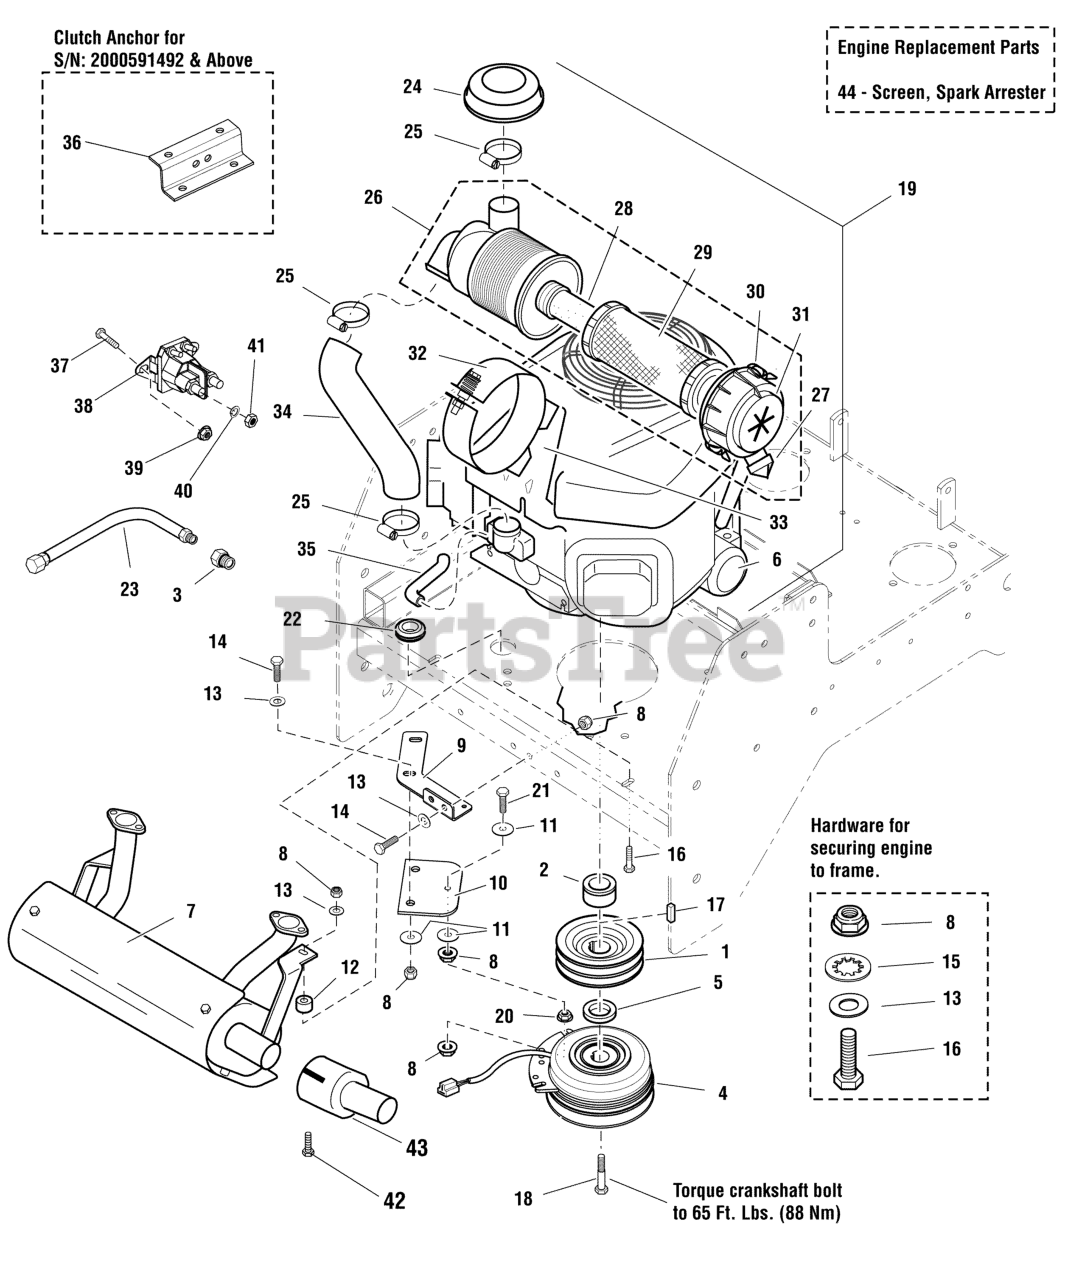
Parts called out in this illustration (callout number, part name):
1	PULLEY CRANKSHAFT (DOUBLE A)
2	SPACER, 1.13 X 1.75 X 1.03
3	ADAPTER, OIL DRAIN
4	* CLUTCH, 5218-134, WARNER
5	SPACER, 1.13 X 1.75 X .375
6	OIL FILTER (49065-2078)
7	MUFFLER, 21HP-25HP KAWASAKI ENGINES
8	NUT, 5/16-18 HEX NYLOCK FLANGE
9	PLATE, CLUTCH ANCHOR
10	CLUTCH ANCHOR PAD
11	WASHER, CLUTCH ANCHOR
12	SPACER, .39 X 1.00 X .80
13	WASHER, 5/16" SAE
14	BOLT, 5/16-18 X 1" GD5 YZ
15	WASHER, 5/16" INT. TOOTH LOCK
16	BOLT, 5/16-18 X 1-3/4" GD5
17	KEY, 1/4 SQ X 1
18	BOLT, CRANKSHAFT 7/16 X 2 3/4
19	ENGINE, 25HP KAWASAKI
20	NUT, 5/16-18 HEX SERRATED FLANGE (LARGE)
21	BOLT, 5/16-18 X 2-1/4 TFL, GD5 YZ
22	GROMMET, 7/8
23	HOSE, OIL DRAIN
24	RAIN COVER
26	AIR FILTER ASSEMBLY
27	RUBBER, Dust Valve
28	AIR FILTER, SECONDARY
29	AIR FILTER, PRIMARY
30	CLAMP, CAP
31	CAP END, FILTER CASE
32	CASE, BRACKET, COMPLETE
33	BRACKET PLATE
34	AIR INLET TUBE
35	BREATHER TUBE
36	ANCHOR, CLUTCH - BLK
37	BOLT, 1/4-20 X 3/4" GD5 YZ
38	SOLENOID-4 POLE 12 VOLT DC (TROMBETTA)
39	NUT, 1/4-20 HEX SERR. FLANGE
40	WASHER, Light Lock, 5/16
41	NUT, Hex Jam, 5/16-24
42	EXTENSION, TAILPIPE, 3" - BLACK
43	SCREW, SELF-TAP, #8-32 X 3/8. WASH HEX, CZ
